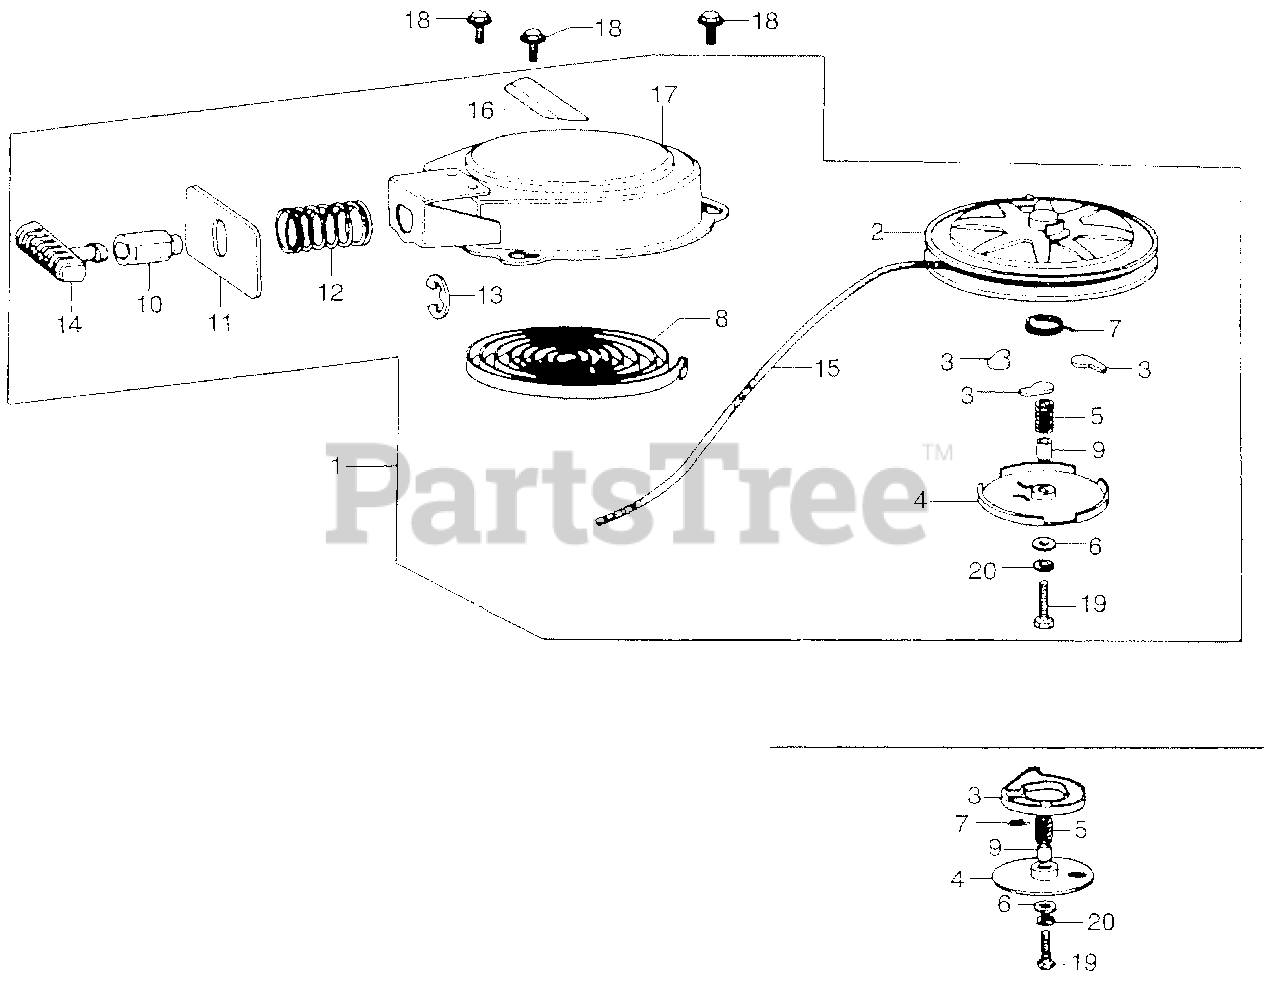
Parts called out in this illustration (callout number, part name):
1	STARTER ASSY., RECOIL (NOT AVAILABLE)
2	PULLEY, RECOIL STARTER
3	RATCHET, STARTER
4	PLATE, FRICTION
5	SPRING, FRICTION
7	SPRING SET
8	SPRING, RECOIL STARTER
10	GUIDE, ROPE
11	PLATE, SEAL (NOT AVAILABLE)
12	SPRING, SEAL PLATE
14	GRIP, STARTER
15	ROPE, RECOIL STARTER (#4X65") (NA USE ALT:08540-ZG921-11)
16	MARK, RECOIL STARTER CAUTION
18	BOLT, FLANGE (6X12)
19	BOLT, HEX. (6X25)
20	WASHER, SPRING (6MM)
